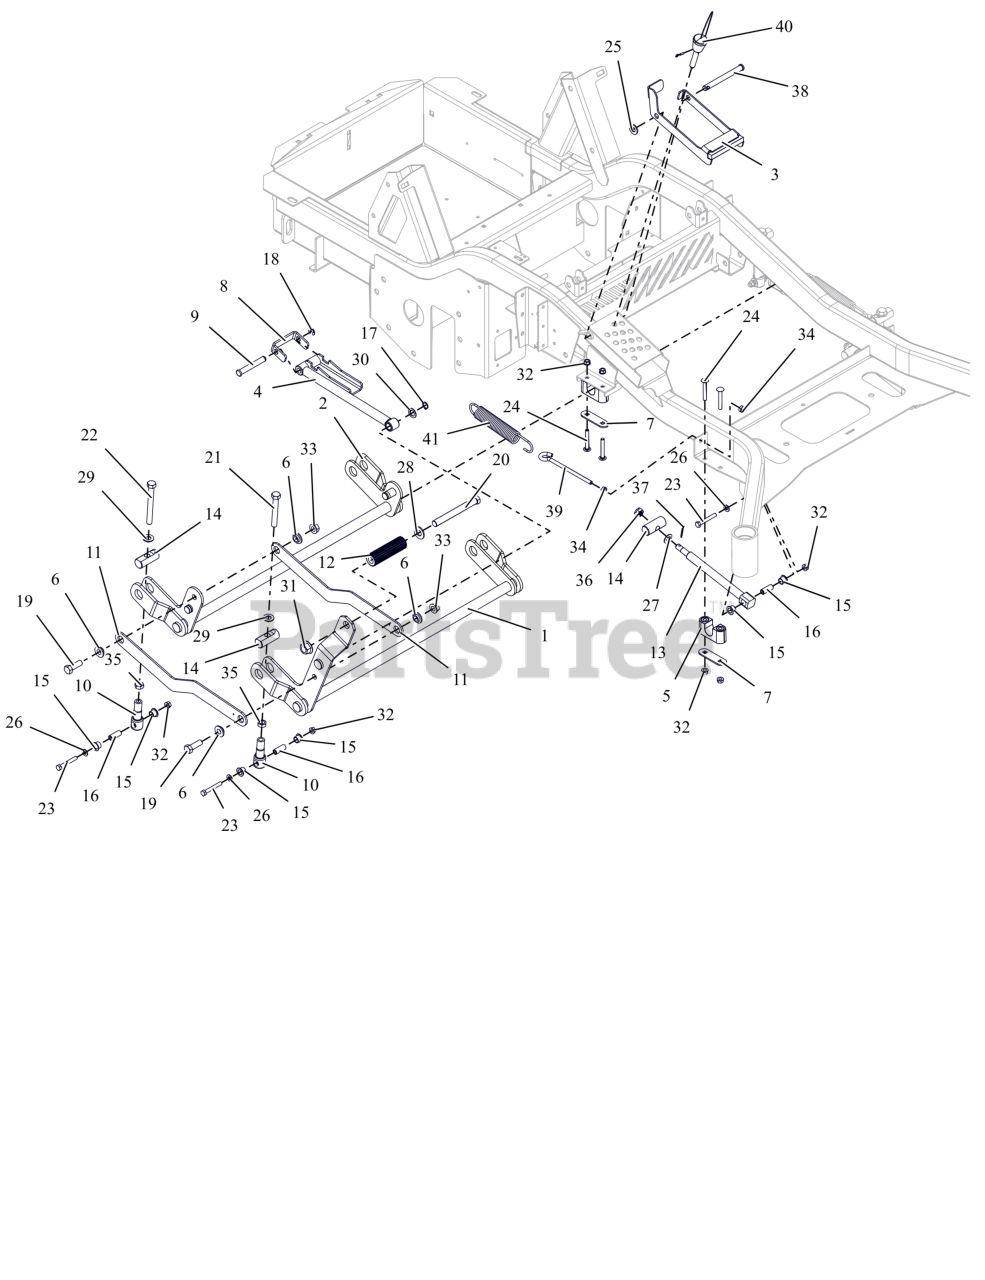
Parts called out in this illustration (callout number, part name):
1	WLDMT, FRONT DECK LIFT PIVOT
2	WLDMT, REAR DECK LIFT PIVOT
3	BRKT, HOC TRANSFER LOCK
4	WLDMT, HOC ARM
5	ASM-BUSHING, DECK LIFT
6	BSHG-FLG .515X.750X.395X1.120
7	PLATE, BEARING SUPPORT
8	BRKT, HOC LINE
9	PIN, .499/.494 x 3.385 CLEVIS
10	LINK, DECK LIFT FORMED
11	LINK, DECK LIFT
12	ROD, FOOT PEDAL (BLACK)
13	DRAG,LINK-HD
14	PIN, DECK LIFT
15	BSHG, FLANGED .50X.625X.50X.062
16	SPCR, .31X.50X1.265
17	RG-RTNG-EXT .625X.050
18	RG-RTNG-EXT .500X.042 (E)
19	BLT,HEX .50-13X1.50 G5 ZCC
20	BLT, HEX .62-11X5.50 G5 FBP
21	BLT, HEX .50-13X3.50F G5 ZCC
22	BLT, HEX .50-13X4.50F G8 ZCC
23	BLT, HEX .31-18X2.25 G5 ZCC
24	BLT, RHSSN.31-18X2.25 G5 ZCC
25	WSHR,FLT .531X1.062X.095 ZCC
26	WSHR,FLT .344X.688X.065 ZCC
27	WSHR, BLVL .531 X 1.000 X .062 MZ
28	WSHRFLT 5/8SAE CARBHARD FBP
29	WSHR, FLT .557X1.040X.102 ZCC
30	WSHR, FLT .630X1.005X.062 ZCC
31	NUT,FLG-TOP LK .625-11 FBP
32	NUT,LK-CTR-FLG .31-18 GF ZCC
33	NUT-LK-CTR-FLG .500-13 GG ZCC
34	NUT-JAM .375-16 G2 ZCC
35	NUT-JAM .500-13 G2 ZCC
36	NUT-SL .50-13
37	PIN,CTR.12X1.25EXTPRSQCT ZC120
38	PIN-SLIC .50X4.97X4.55 -ZCC
39	BOLT,.38-16 X 5.25-.62 DIA EYE
40	PIN- MAGNETIC .50X2.70
41	SG-TENS .162X1.25X8.25 WLD 25
